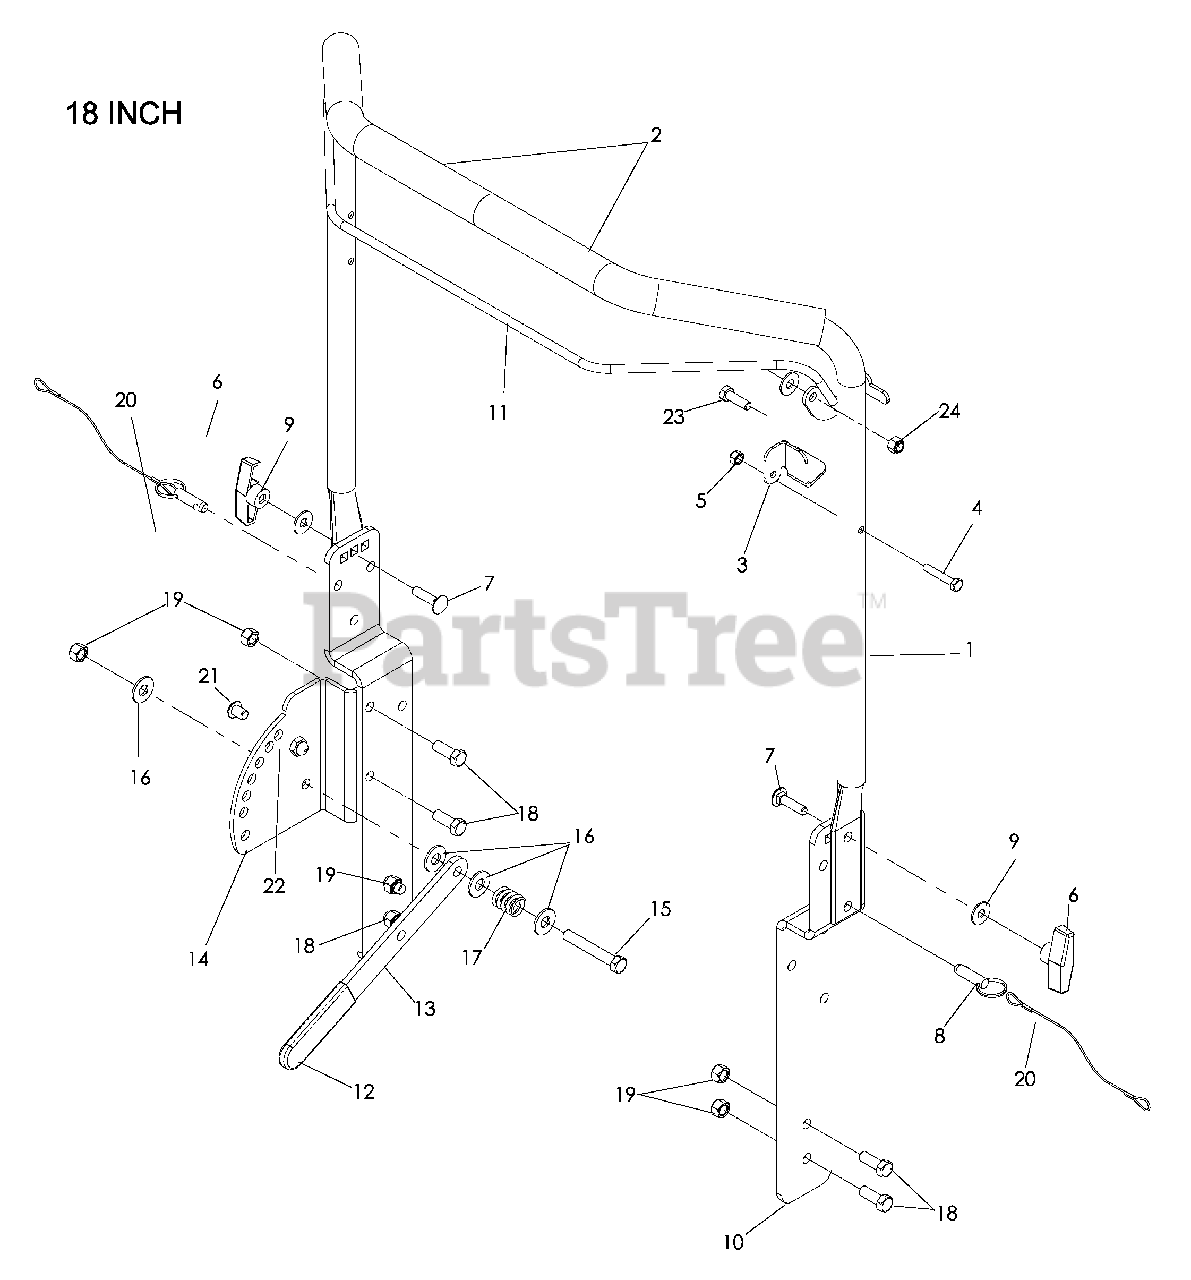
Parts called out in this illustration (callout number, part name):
4	HCS ¼-20 x 1½
5	NUT ¼-20 NYLOC
7	RHSNB 5/16-18 x 1¼
9	WASHER 5/16 FLAT
10	HANDLE SIDE
12	GRIP, LEVER
14	PLATE, HEIGHT
15	HCS 3/8-16 x 2½
16	WASHER 3/8 FLAT
18	HCS 3/8-16 x 1
19	NUT 3/8-16 NYLOC
21	SCREW 3/8-16 BUTTON HD
22	NUT 3/8-16 ACORN
23	HCS 5/16-18 x 1
24	NUT 5/16-18, NYLOC
